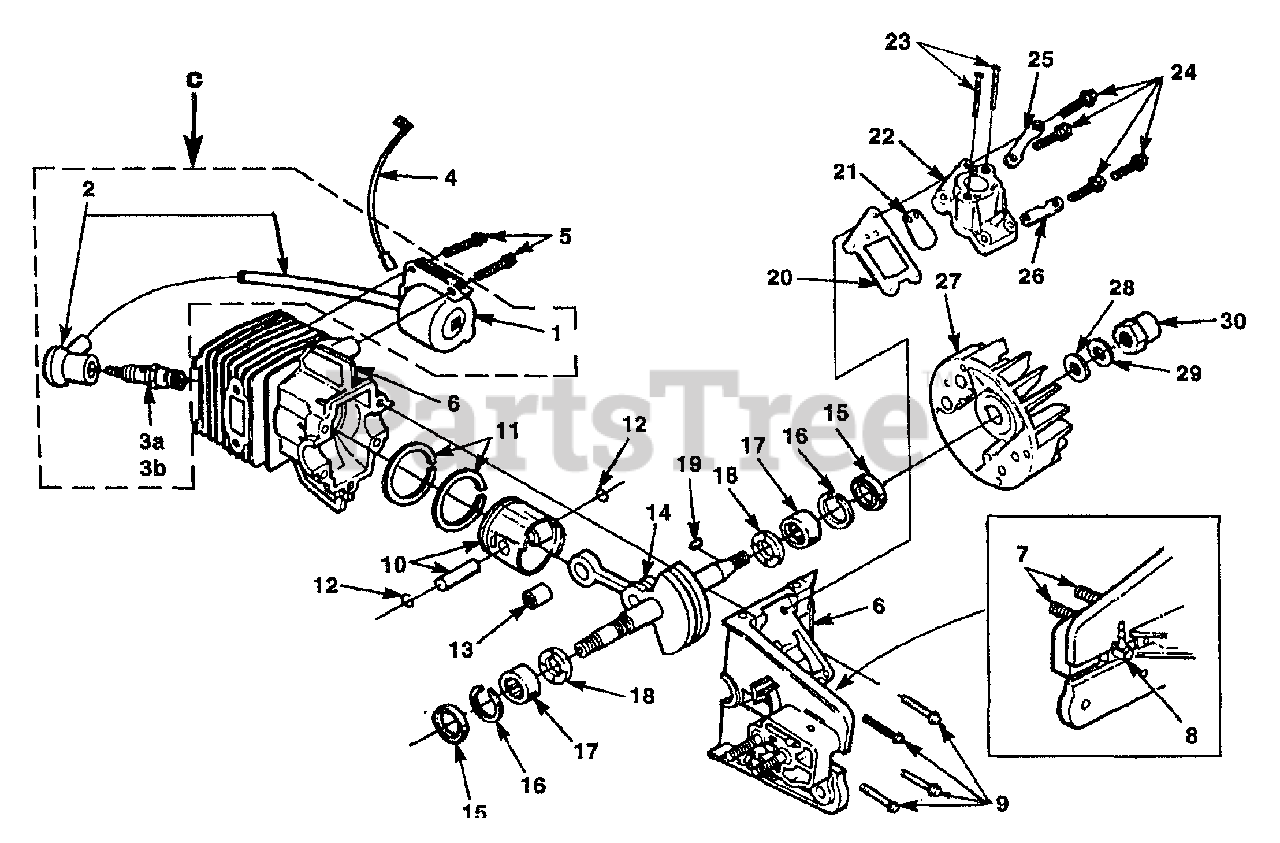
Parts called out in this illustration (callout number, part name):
1	MODULE-Ignition
2	TERMINAL-High Tension Lead
3A	SPARK PLUG (DJ-7Y)
3B	SPARK PLUG (RDJ-7Y) (UT10713, 10715-A)
4	LEAD-Ground
5	SCREW-Machine Hex Hd. (8-32 X 7/8")
6	CRANKCASE & CYLINDER
7	BOLT-Guide Bar
8	FITTING-Tube
9	SCREW-Sems Hex Hd. (10-24 X 1 1/8")
10	PISTON & PIN
11	PISTON RING
12	RING-Retaining
13	BEARING-Needle
14	CRANKSHAFT
15	SEAL-Shaft
16	RING-Retaining
17	BEARING-Needle
18	BEARING-Thrust
19	KEY-Woodruff
20	GASKET-Manifold
21	REED
22	MANIFOLD-Intake
23	SCREW-Plastite (#8-16 X 1 3/4")
24	SCREW-Hex Washer (8-32 X 5/8")
25	WASHER-Intake Manifold
26	WASHER-Intake Manifold
27	ROTOR & STARTER PAWLS
28	WASHER-Flat
29	WASHER- Lock
30	NUT-Guide
C	IGNITION KIT
